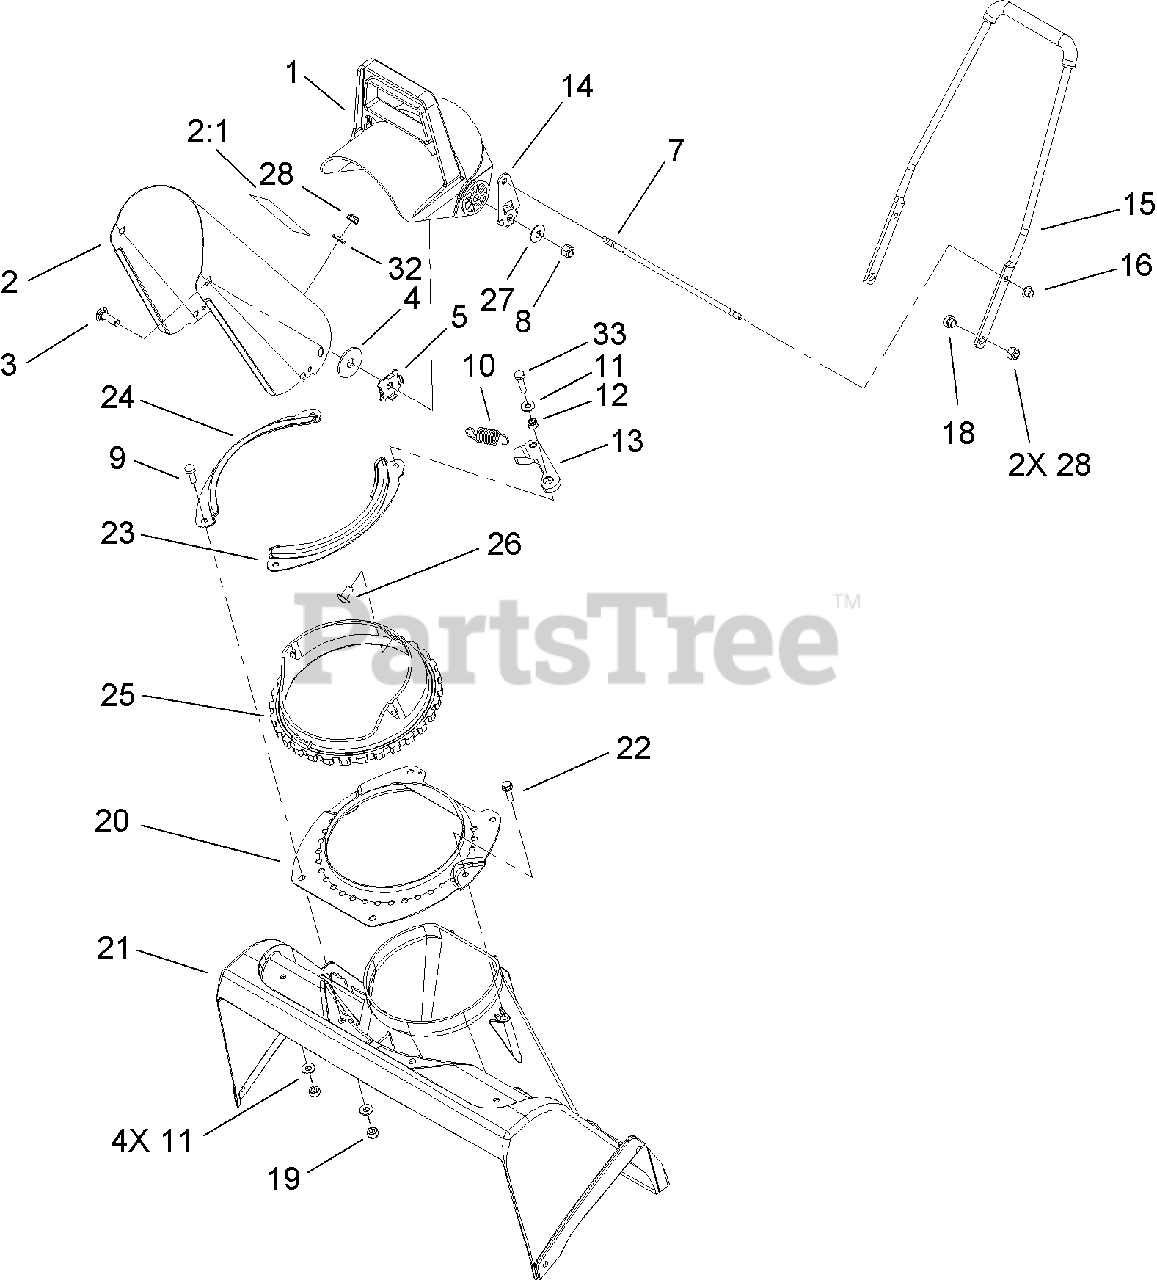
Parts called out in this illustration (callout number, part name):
1	CHUTE-DEFLECTOR
2	CHUTE ASM
2:1	DECAL-DANGER
3	SCREW-CARR
4	WASHER-RUBBER
5	PLATE-FRICTION
7	LINKAGE-CHUTE
8	NUT-LOCK, NI
9	SCREW-HH
10	SPRING-EXTENSION
11	WASHER-FLAT
12	SPACER-BLADE, ROTOR
14	CHUTE-PIVOT ARM
15	HANDLE-FOAM
16	PUSHNUT-CAP, WASHER
18	SPACER-FLANGED
19	NUT-LOCK, NI
20	RING-SUPPORT, CHUTE
21	HOUSING-ROTOR, UPPER
22	SCREW-HWH
23	RETAINER-CHUTE, LH
24	RETAINER-CHUTE, RH
25	RING-CHUTE
26	SCREW-CARR
27	WASHER-BELLEVILLE
28	NUT-LOCK, NI
32	WASHER-FLAT
33	SCREW-HH
